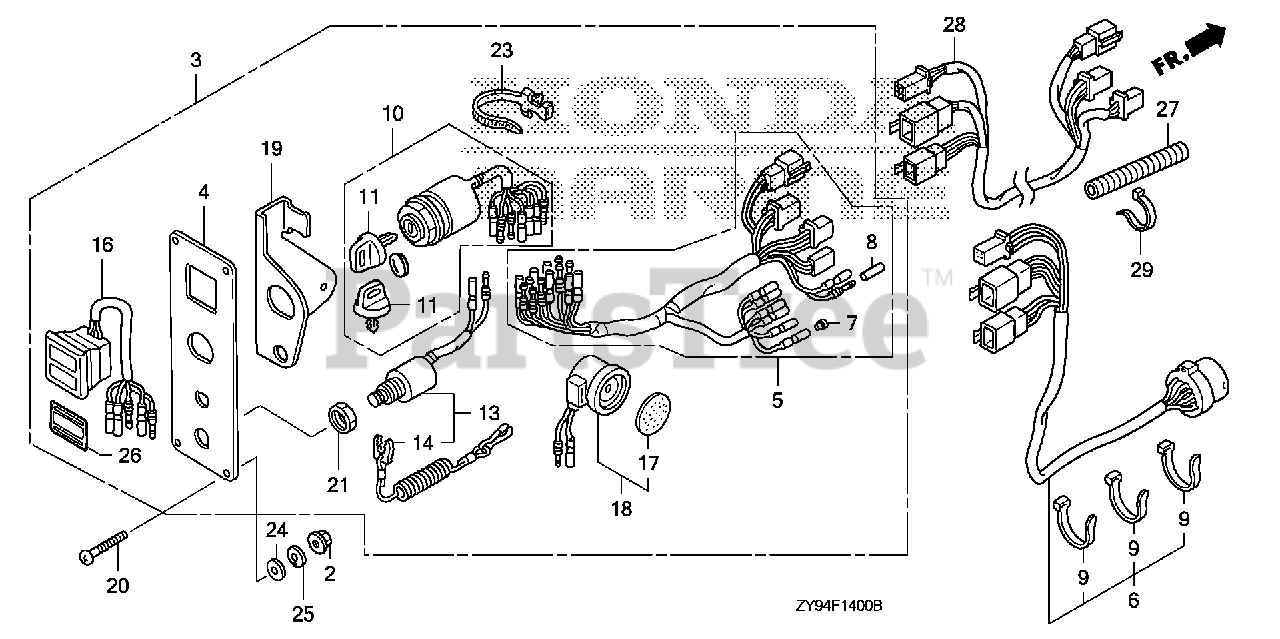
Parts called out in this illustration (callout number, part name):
2	NUT, FLANGE (5MM) DUAL QTY = (8) (SINGLE)
3	PANEL ASSY., CONTROL (2-LED)
4	PANEL, CONTROL
5	HARNESS ASSY., SWITCH PANEL
6	CABLE ASSY., SWITCH PANEL
7	PLUG, CONNECTOR (INNER) (TROLLING CONTROL)
8	PLUG, CONNECTOR (OUTER) (ENGINE NO.)
9	TIE, CABLE (NATURAL 2.4X92) Use up to Frame SN 1300359.
10	SWITCH ASSY., COMBINATION DUAL QTY = (2) (SINGLE)
10	SWITCH ASSY., COMBINATION (SINGLE) (DUAL)
11	KEY ASSY., COMBINATION SWITCH (35100-ZV5-003 ONLY) DUAL QTY = (4) (SINGLE)
13	SWITCH ASSY., EMERGENCY STOP
14	WIRE, EMERGENCY (SINGLE) (DUAL)
16	LAMP ASSY., INDICATION (2-LED) DUAL QTY = (2) (SINGLE)
17	PLATE, TURN SIGNAL BUZZER DUAL QTY = (2) (SINGLE)
18	BUZZER, WARNING DUAL QTY = (2) (SINGLE)
19	BRACKET, BUZZER DUAL QTY = (2) (SINGLE)
20	SCREW, PAN (5X40) DUAL QTY = (8) (SINGLE)
21	NUT, HEX. (16MM) DUAL QTY = (2) (SINGLE)
23	BAND, WIRE HARNESS (150MM) (NATURAL) DUAL QTY = (2) (SINGLE)
24	WASHER, PLAIN (5MM) DUAL QTY = (8) (SINGLE)
25	WASHER, SPRING (5MM) DUAL QTY = (8) (SINGLE)
26	MARK, SWITCH PANEL DUAL QTY = (2) (SINGLE)
27	TUBE, CORRUGATED (28MM)
28	CABLE ASSY., REMOTE CONTROL EXTENSION Use from Frame SN 1300029.
29	BAND, SELF-LOCK Use from Frame SN 3000253.
